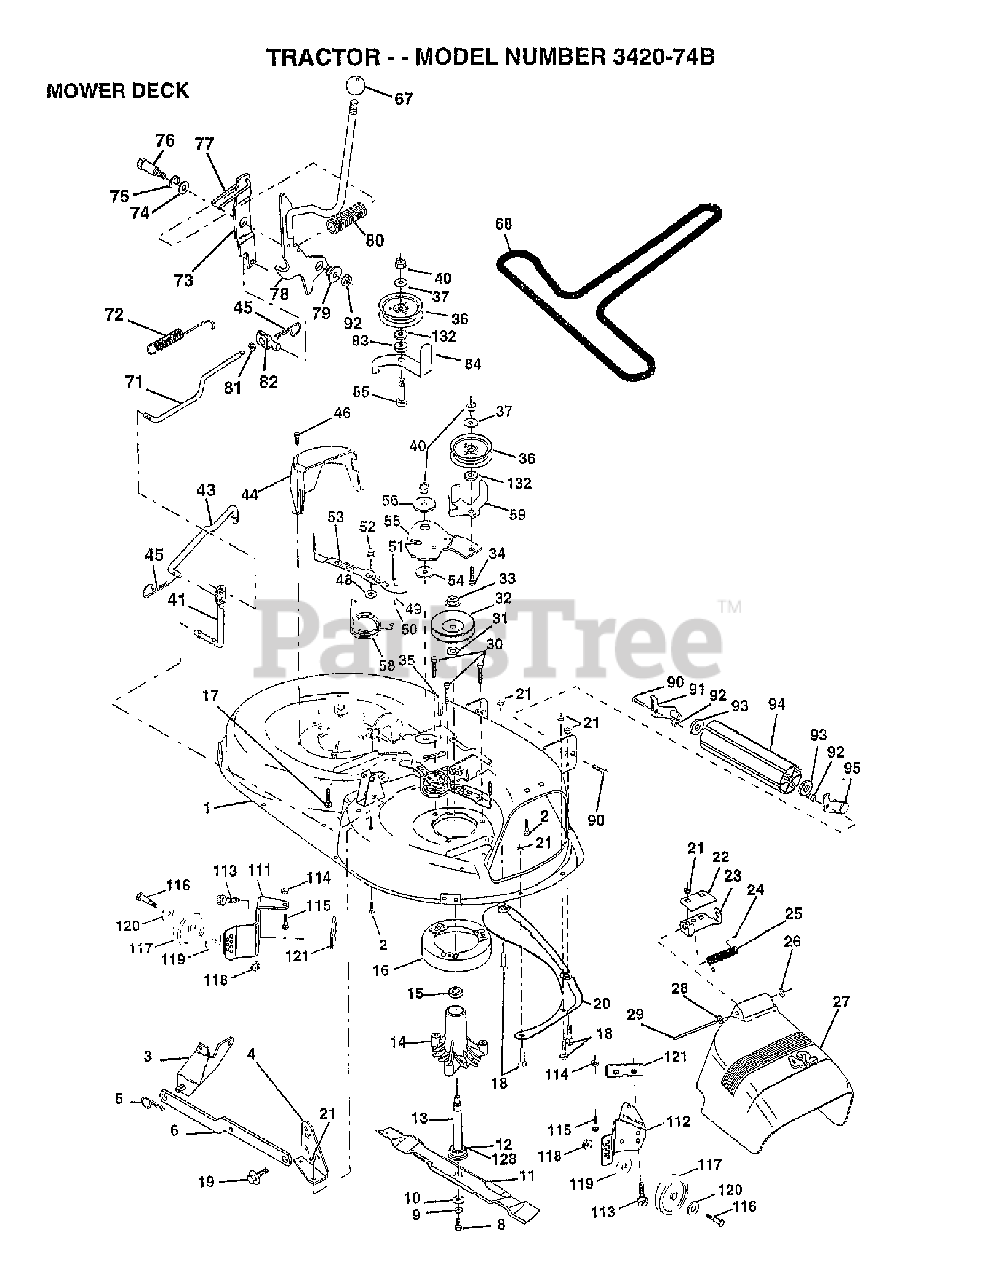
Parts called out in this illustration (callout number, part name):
2	BOLT
3	BRKT ASM SWAY BAR
4	BRKT DECK SW BAR
5	RETAINER SPRING
8	BLADE BOLT
10	WASHER.BLADE
11	BLADE.42".MULCH
12	BEARING.BALL.#6204.(MANDREL)
13	SHAFT ASM VENT
14	HSG MANDREL
17	BOLT
18	BOLT
19	BOLT SHD 5/16-18
21	LOCKNUT
23	DEFLECTOR BRACKET
24	CAP-SLEEVE LT
25	DEFLECTOR SPRG T
26	NUT PUSH M
27	SHIELD.DEFLECTOR.MOWER.42".BLK
28	WASHER
29	ROD.HINGE
30	Hex Washer Head Bolt, .313-18 X 1.19
31	WASHER
34	BOLT
35	FASTENER.XMAS.TREE
36	IDLER-FLAT GT
40	LOCKNUT
41	PIVOT ROD
43	CLUTCH ROD
44	MANDREL GUARD LH
45	RETAINER M
46	SCREW.1/4-20X5/8
50	BOLT
52	BOLT, SHOULDER LT
59	GUARD, BELT
67	PIGTAIL, LIGHT
68	V-BELT TRIPATH
72	RETURN SPRING
73	ARM CLUTCH SECONDARY
75	RING CLIP
79	BUSHING.FLANGE.E-RING.GROOVE
80	SPRING-CLUTCH
81	NUT
82	TRUNION T
84	KEEPER.BELT.IDLER
90	BOLT
91	Roller Bracket Assembly, LH
92	NUT
94	MANUAL, OPERATOR
113	Screw, Lt
116	BOLT
117	GUAGE WHEEL GT
118	LOCKNUT
119	WASHER
121	BRACKET.EXTRUDED.GAGE.WHEEL
128	WASHER FELT
132	WASHER GT
